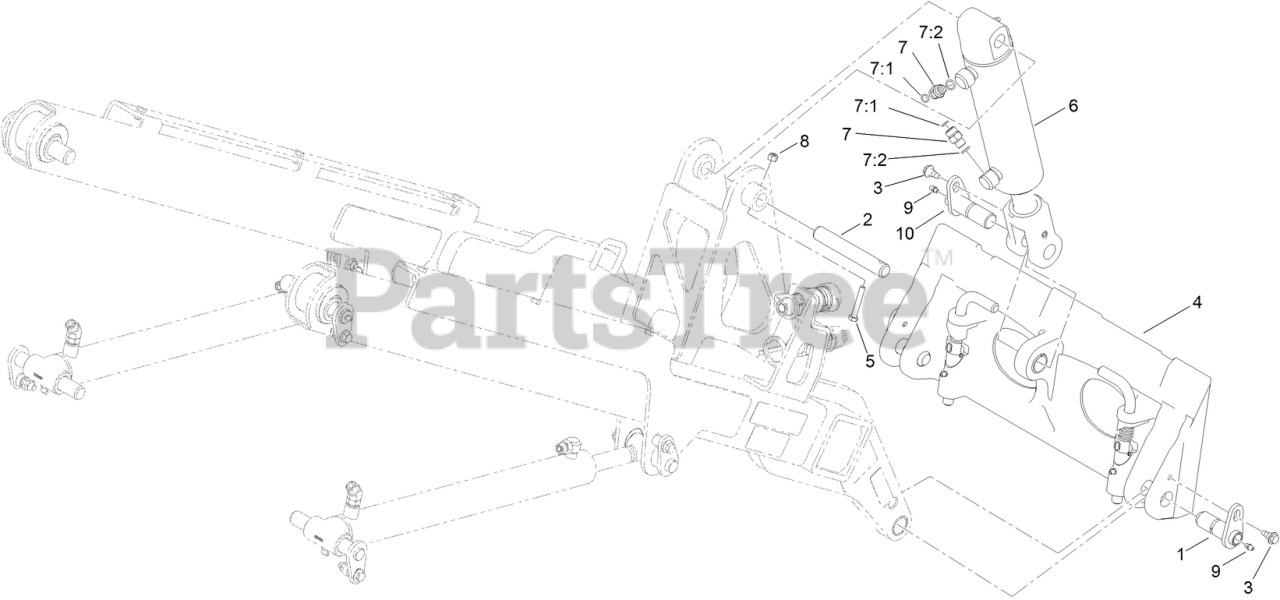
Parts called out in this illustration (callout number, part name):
1	PIN-PIVOT
2	PIN-LOCKING
3	BOLT-SHOULDER
4	QUICK ATTACH ASM
5	SCREW-HH
6	HYD CYL ASM
7	FITTING-STRAIGHT
7:1	O-RING
7:2	O-RING
8	NUT-LOCK, NI
9	FITTING-GREASE
10	PIVOT PIN ASM
